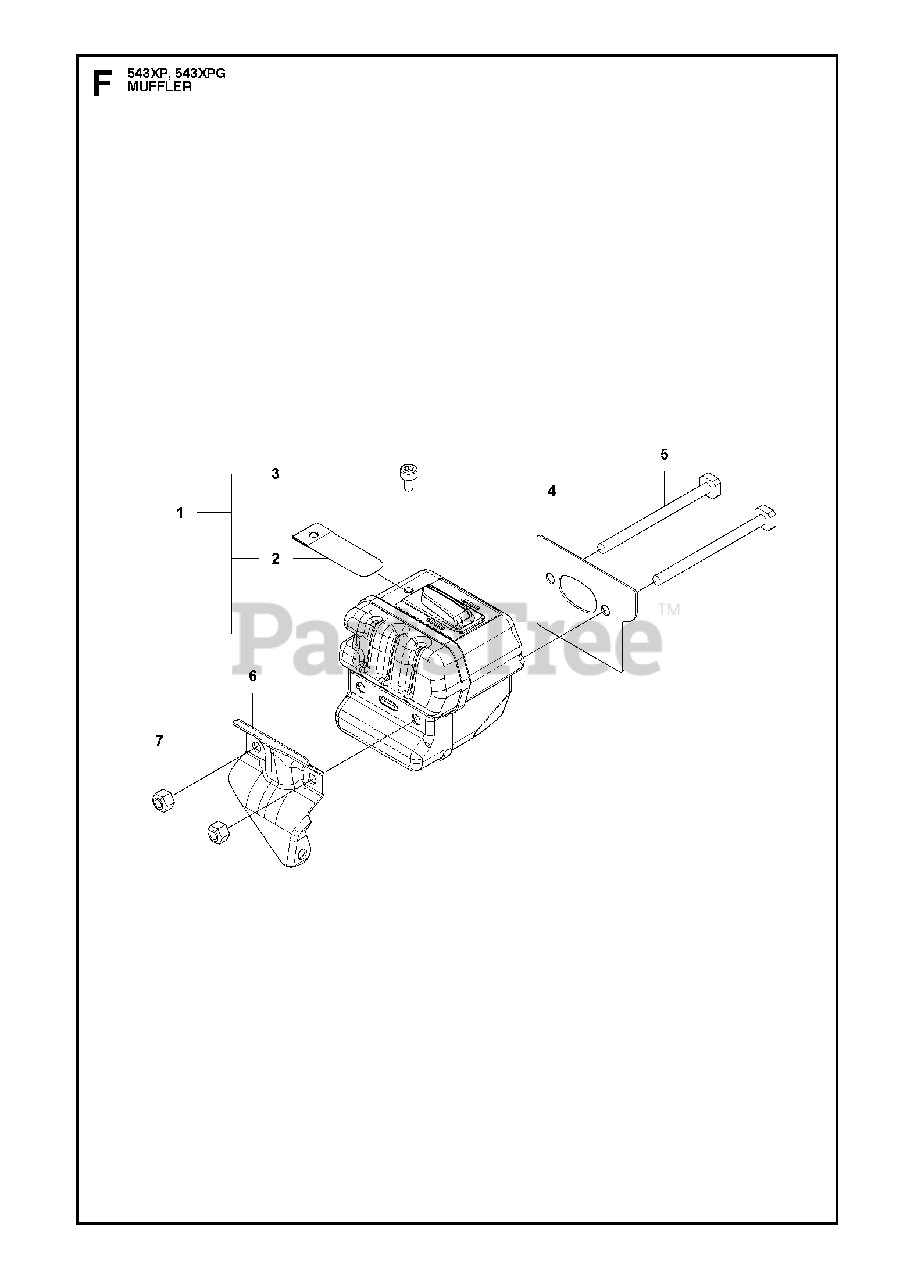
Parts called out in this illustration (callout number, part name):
1	MUFFLER ASSY
2	SPARK AARRESTOR SCREEN
3	BOLT
5	BOLT
6	BRACKET MUFFLER
